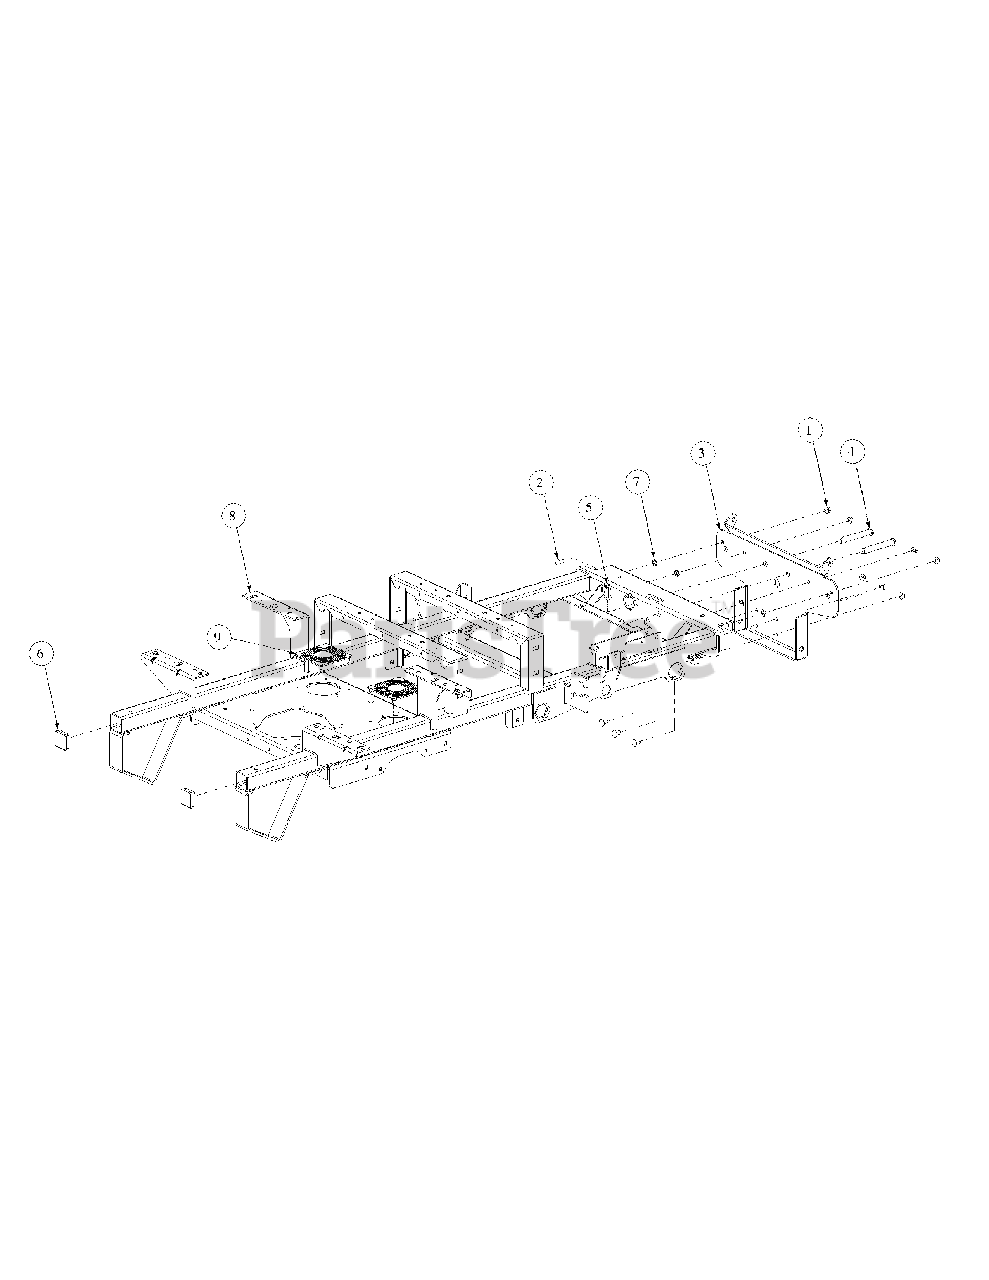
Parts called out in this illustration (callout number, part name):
1	Hex Nut, 3/8-16 Flange Lock
2	Carriage Bolt, 3/8-16 x .75 Long
3	Bracket Assembly, Frame, Front
4	Clevis Pin, .625 Dia x 4.375 Long
5	Linch Pin, 3/16 Dia.
6	Plug, Square Tube
7	Push Retainer, 3/8
8	Frame Assembly
9	Cover, Hydro Fan
